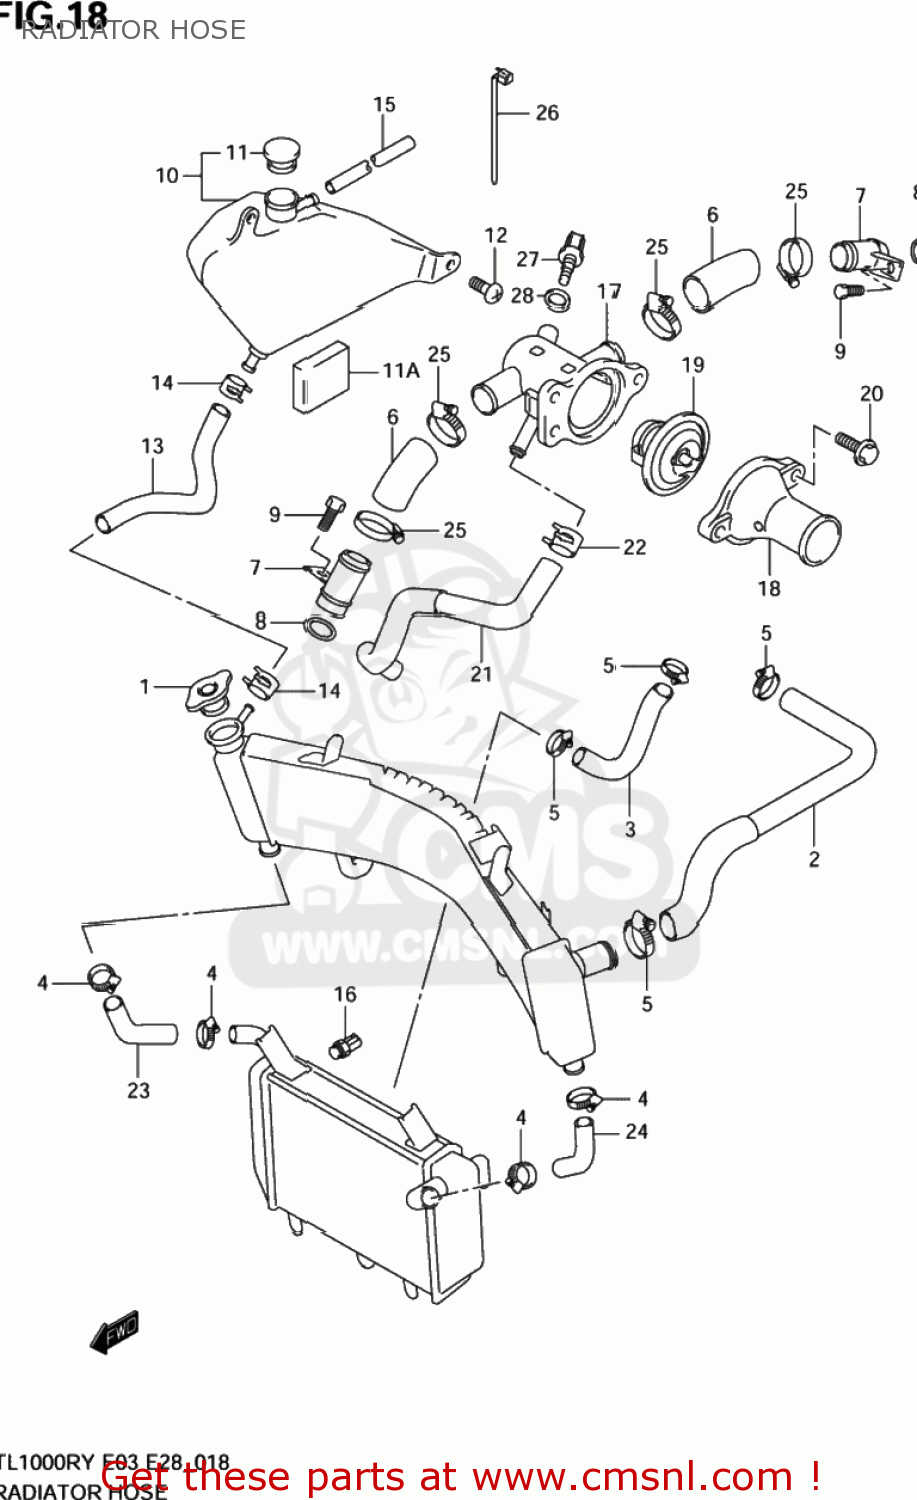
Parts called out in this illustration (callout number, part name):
1	CAP COMP,RADIATOR
2	HOSE,RADIATOR INLET
3	HOSE,RADIATOR OUTLET
4	CLAMP
5	CLAMP
6	HOSE,CONNECTOR INLET
7	UNION,CONN HOS
8	O RING(D:3.2,ID:17.8)
9	BOLT,STRANGER
10	TANK ASSY,RESERVOIR
11	CAP,RESERVOIR TANK
11A	CUSHION,HEADLAMP COVER
12	BOLT
13	HOSE,RESERVOIR TANK INLET
14	CLIP
15	HOSE,RESERVOIR TANK OVERFLOW
16	SWITCH,RADIATOR FAN
16A	O-RING
17	CONNECTOR,THERMOSTAT INLET
18	CAP,THERMOSTAT CONNECT
19	THERMOSTAT,WATER 82 DEG
20	BOLT
21	HOSE,CONNECTOR TO WATER PUMP
22	CLAMP
23	HOSE,RADIATOR JOINT
24	HOSE,RADIATOR JOINT,L
25	CLAMP
26	CLAMP(L:125)
27	SENSOR,WATER TEMP
28	GASKET(12X17X1) (NAS)
